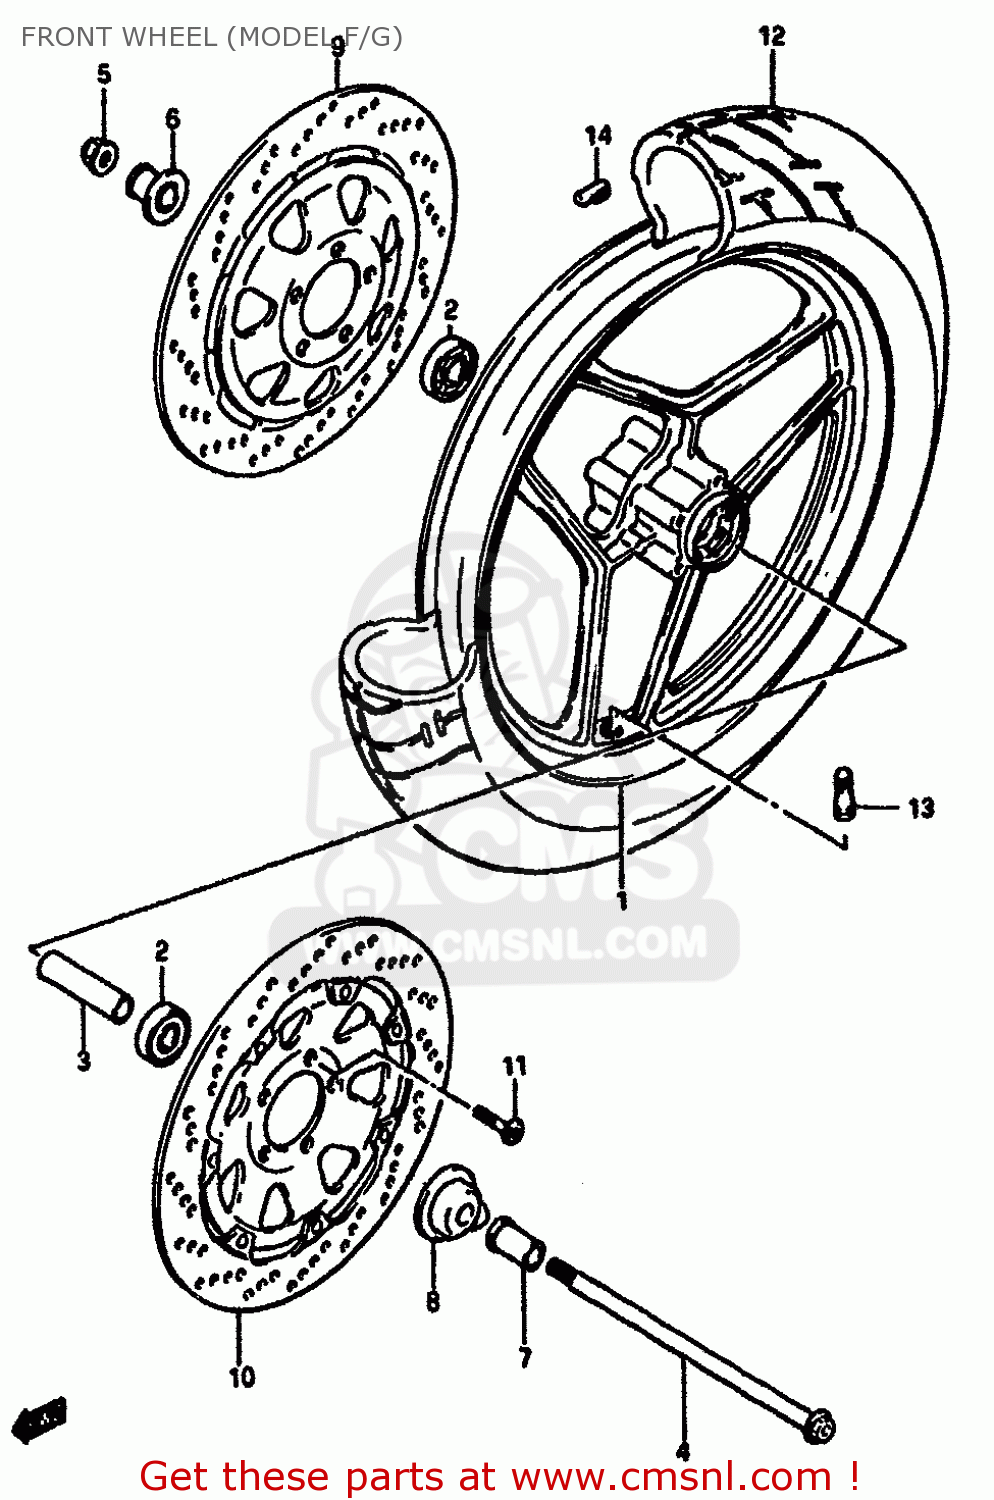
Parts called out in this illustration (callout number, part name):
1	WHEEL,FRONT (2.50X18)
2	BEARING
3	SPACER(15.3X21.7X77)
4	AXLE, FRONT
5	NUT
6	SPACER,FR HUB BEARING,R
7	SPACER
8	BOX ASSEMBLY,SPEEDOMETER GEAR
9	DISC,BRAKE
10	DISC,BRAKE
11	BOLT
12	TIRE,FRONT
13	VALVE,TIRE
14	BALANCER,WHEEL
